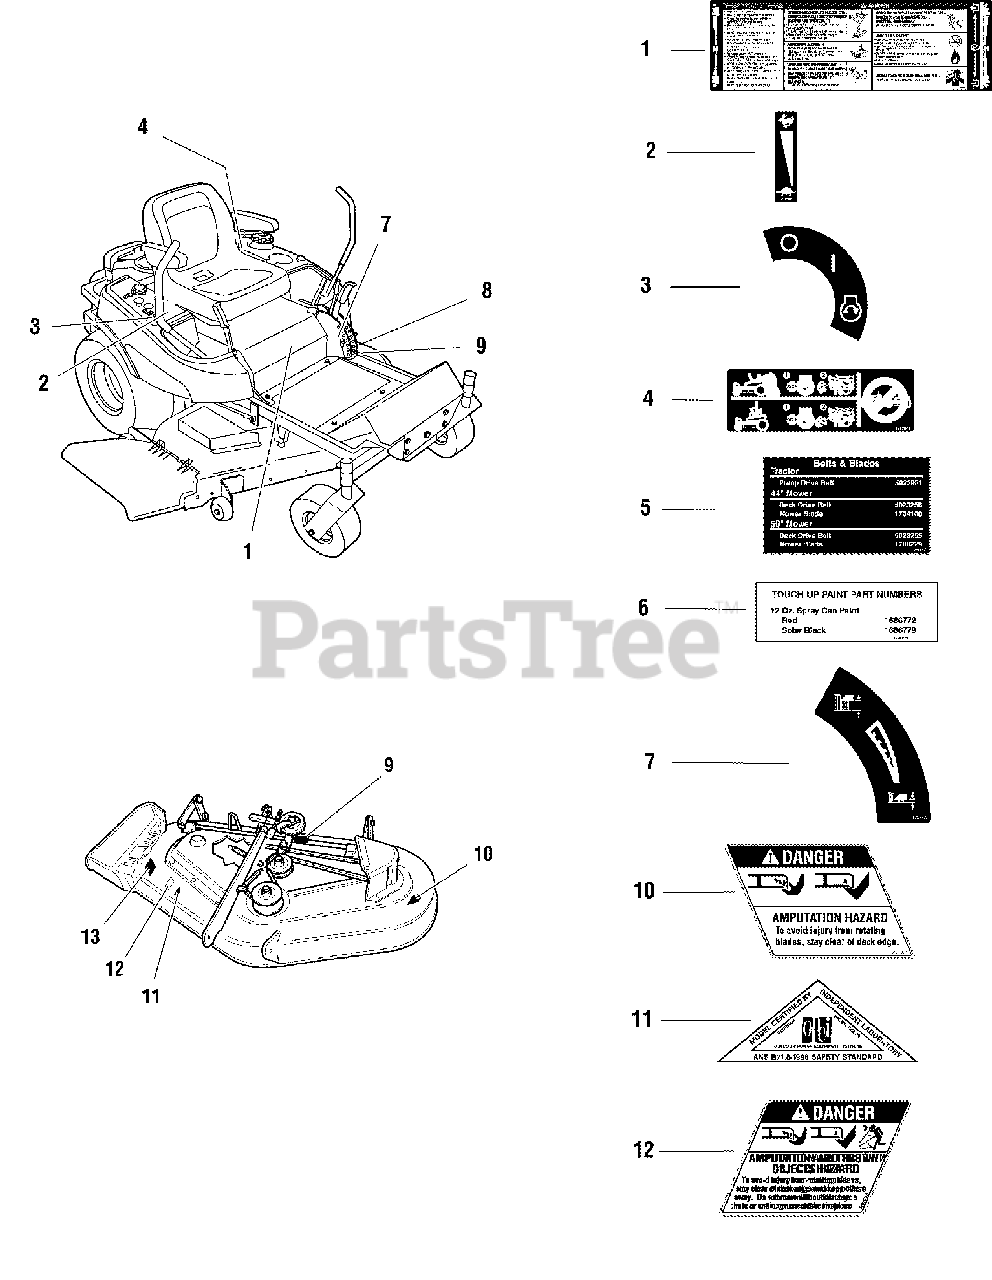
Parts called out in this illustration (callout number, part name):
1	DECAL, MAIN
2	DECAL, THROTTLE CONTROL
3	DECAL, IGNITION SWITCH
4	DECAL, CZT HYDRO RELEASE
5	DECAL, BELT & BLADE
6	DECAL-TOUCH UP PAINT
7	DECAL, HEIGHT OF CUT
8	DECAL, US PATENT, ZTR
9	DECAL, ID PLATE
10	DECAL, DANGER, MOWER
11	DECAL-OPEI CERTIFIED ANSI B71.12003 GOLD
12	DECAL, DANGER, MOWER DISCHARGE
